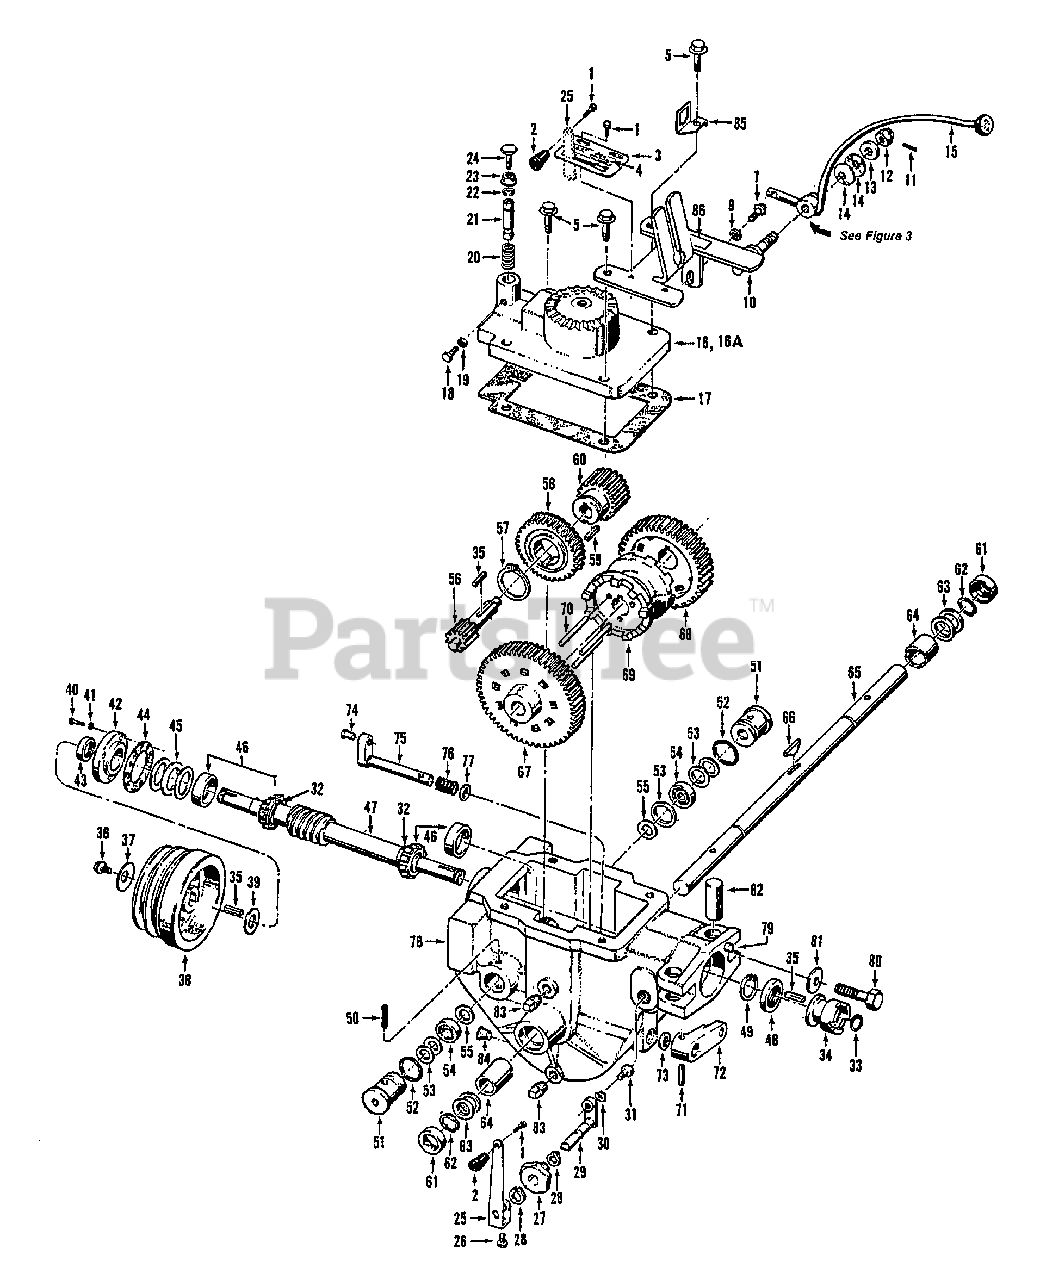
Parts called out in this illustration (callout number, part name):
1	SCR 10-32
2	KNOB-TAPERED
3	PLATE-TINE ENGAGE W/DECAL #2720 REF.#4
4	DECAL-TINE ENGAGE
5	SCR-HFLK 3/8-16X1.50
7	SCR-HFLK 5/16-18X.75 ZP
8	THIS REF.# NOT USED
9	WASHER-FLAT 5/16 SAE
10	BRKT-H HOOD, W/ DECAL #2721 REF.#86
11	PIN -- SPRING, 1/8" DIAMETER
12	NUT-HEX 1/2-20
13	WASHER-SHOULDER ZP (SHLDR FACES DISC WASHERS)
14	WASHER-1.97X1X.118 (CONC SURF FACE EACH OTHER)
15	LEVER, WHEEL SPEED SHIFT (SHOWN FOR REF. ONLY)
16	COVER-TRANS RED
16A	ASSM-TRANS COVER OPC (COMPL. ASSY W/ NUETRAL SPRING ASSY PARTS (#'S 18-24)
17	GASKET-TRANS COVER
18	SCR-HH 5/16-18X1.0 G5 ZP (RET. NEUTR. PLUNGER)
19	NUT-HEX 5/16-18 ZP
20	SPRING-REV PLUNGER ZP
21	ASSM-NEUTRAL PLUNGER W/CLIP RING #9504 REF. #22
22	RING-KLIP EXT .594 ID ZP (RET. NEUTR. PLUNGER)
23	NUT-HFLK 3/8-16 ZP
24	SCR 3/8-16X1.5 UNC-2AG
25	LEVER-ECCENTRIC RED (SEE REF.#'S 1-4)
26	SCR-HH 1/4-20X.5 GR5 YEL
27	BUSHING-.87X.5X.62 ECC
28	RING-RETAINING 5100-50 (SNAP RING)
29	ECCENTRIC -- SHAFT, TINES/PTO CLUTCH LEVER
30	WASHER-LK .25 HI-COLLAR
31	SCR-HXSKT 1/4-20X.38 G8
32	WASHER-#1.25X.75X.06 (DRIVE SHAFT)
33	RING-RETAIN EXT .707 ID (SNAP RING)
34	KIT-CLUTCH DOGS TILLER (POWER UNIT)
35	KEY-.188 SQX1.0 (USE ON DRVE AND PNION SHAFTS)
36	SCR-HH 5/16-24X.75 G5 ZP
37	WASHER-.827X.331X.098 (CONCAVE)
38	PULLEY-TRANS MACH
39	WASHER-SHLDR HARDENED
40	SCR-HH 1/4-20X.75 G5 ZP
41	WASHER-LK .25 ZP
42	COVER-FRONT
43	SEAL-PINION SHAFT FRONT
44	GASKET-BRG COVER FRONT
45	SHIM-1.75X1.5X.01
45	SHIM-1.75X1.5X.03
45	SHIM-1.75X1.5X.005
45	SHIM-1.75X1.5X.062
46	KIT-BRG CONE&RACE-DRIVESHAFT (CONE & CUP SOLD AS SET ONLY)
47	KIT-TRANS DRSHAFT HORSE, MN DRVE, PWR UNIT
48	SEAL-OIL DRIVESHAFT REAR
49	RING-RETAINING 5000-181 (SNAP RING)
50	PIN-SPIROL .25 X 2.0 (RET. #1060A PLG REF. #51)
51	PLUG-PINION BRG W/RING #9604 REF.#52
52	RING-O 1 ID
53	SHIM-1.234X1.015X.033
53	SHIM-1.234X1.015X.062
53	SHIM-1.234X1.015X.01
54	BRG-BALL (7 BALLS)
55	WASHER-# 1X.484X.06 (1 USED ON LT & RT SIDES)
56	GEAR-SPLINE 10 TEETH MACH
57	RING-RETAINING 5100-150 (SNAP RING)
58	GEAR-WORM 36 TEETH MACH
60	GEAR-SPUR 20 TEETH MACH
61	SEAL-OIL WHEELSHAFT
62	RING-HEAVY EXT .906 ID (SNAP RING)
63	SHIM-1.375X1.015X.062
63	SHIM-1.375X1.015X.03
63	SHIM-1.375X1.015X.015
63	SHIM-1.375X1.015X.01
63	SHIM-1.375X1.015X.005
64	BUSHING-1.25X1.005X1.5
65	KIT-WHEELSHAFT (INCL #9357 KEY REF.#66, & 2 #9511 RET. RINGS REF.#62
66	KEY-HI PRO .25X1.812
67	GEAR-SPUR 56 TEETH MACH
68	GEAR-SPUR 46 TEETH MACH
69	CLUTCH-MACH
70	PIN-CLUTCH .25 2.65
71	PIN-SPIROL .188 X 1.25
72	LEVER-ECC. #1029
73	SEAL-OIL ECCENTRIC
74	PIN-.375 X .72
75	SHAFT-ECCENTRIC HORSE TLR
76	SPRING .845 X 1.25
77	WASHER # .875 X .65 X .06
78	CASE-TRANS W/PIN #9359 REF.#79
79	PIN-DRIVE .375X.75 ZP
80	SCR-HH 1/2-13X2.0 G5 ZP
81	WASHER-DISC SPRING (CONCAVE)
82	POST (TC)W/ THREADED HOLE FOR #9560 BOLT #80
83	PLUG-PIPE 1/4 NPT (OIL LEVEL CHECK & DRAIN)
84	PLUG-CAP (RED)
85	CLIP-CONNECTOR
86	DECAL-FWD INTERLOCK WIRE
